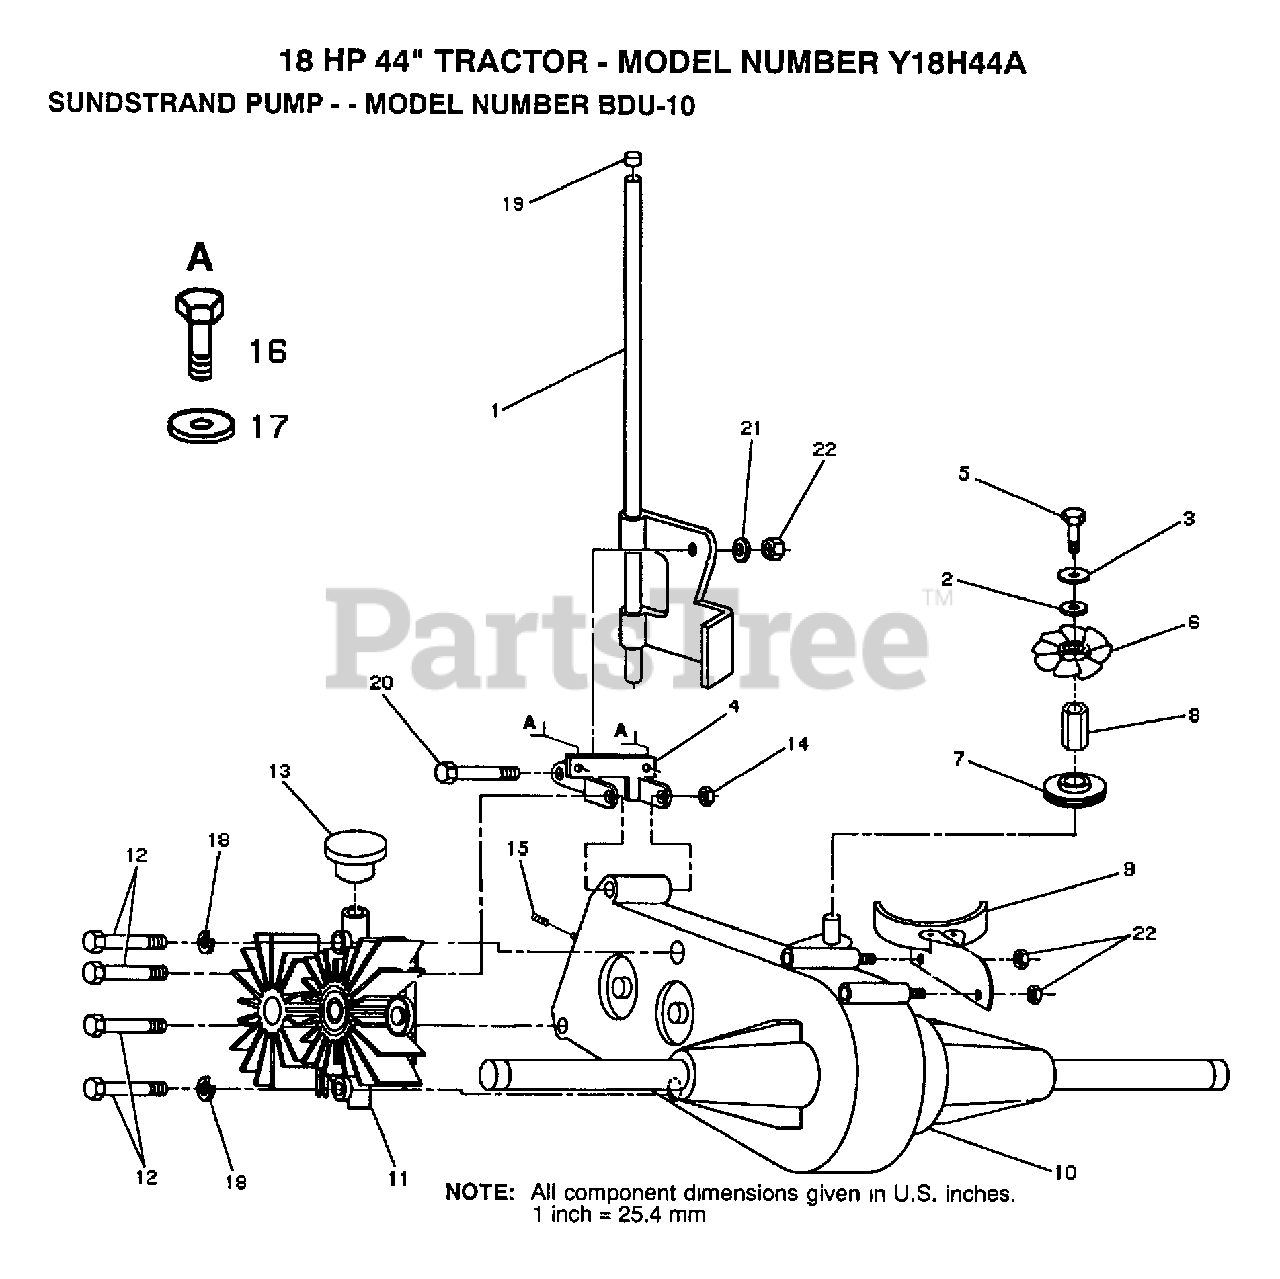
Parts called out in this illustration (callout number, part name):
1	CONTROL ASSY
2	WASHER
3	LOCKWASHER
4	BRACKET
6	FAN
7	PULLEY TRANSAXLE
8	STANDOFF
9	GUARD ASSY
10	TRANSAXLE.AGRIFAB
11	PUMP.BDU-10S-114
12	BOLT
13	PUMP.2003081.
15	SPRING
18	LOCKWASHER
19	PLUNGER CAP T
20	BOLT T
21	WASHER T
